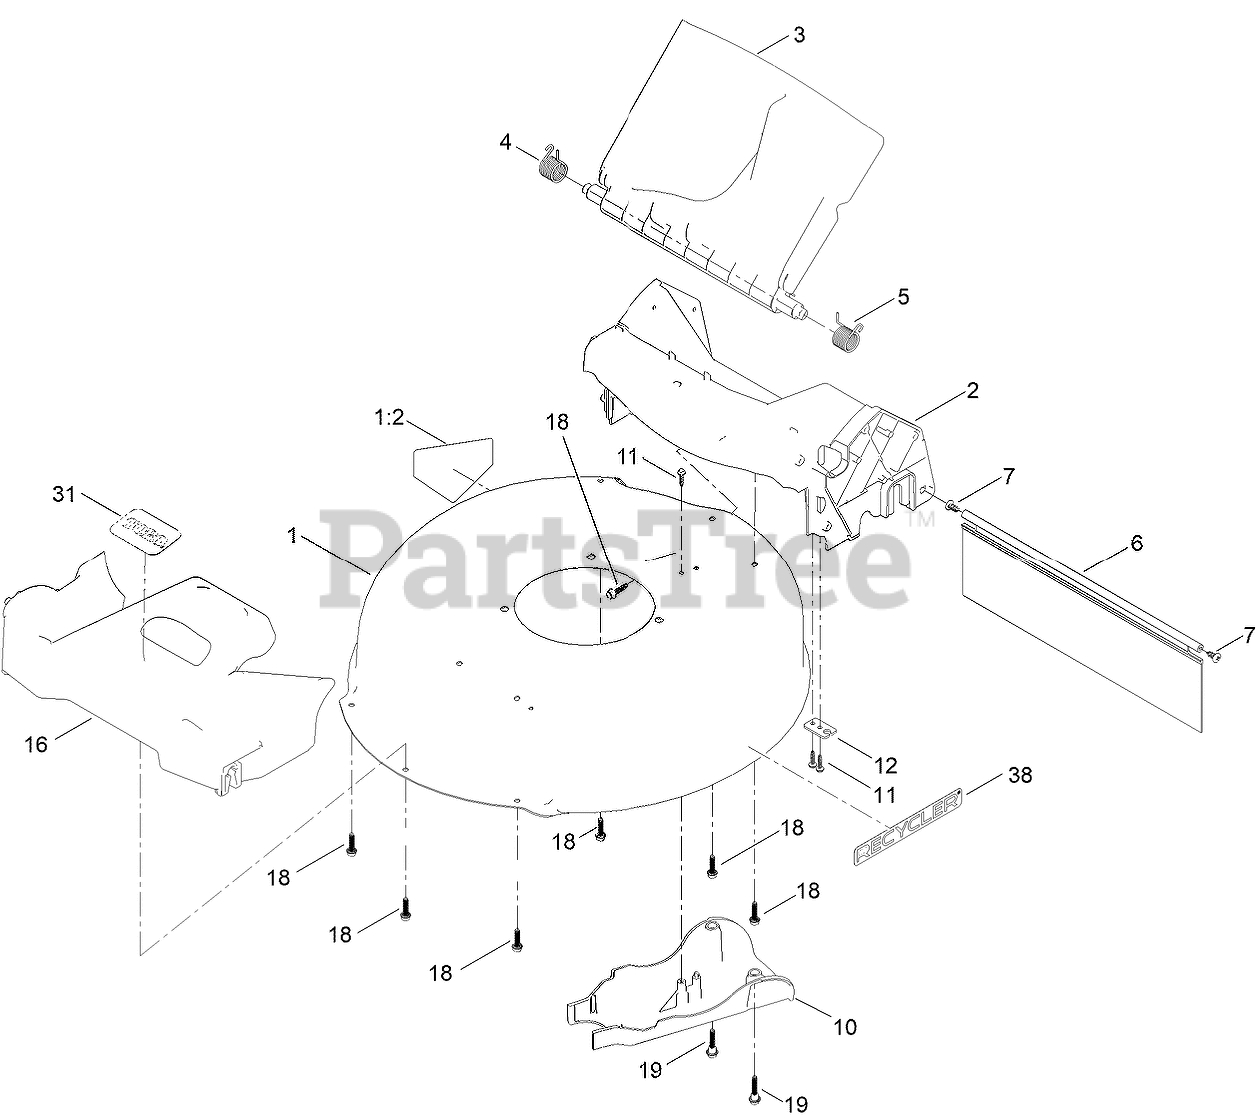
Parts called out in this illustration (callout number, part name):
1	HOUSING ASM
1:2	DECAL-DANGER
2	CHUTE-SP/AWD, 21 IN
3	DEFLECTOR-REAR ASM
4	SPRING-TORSION
5	SPRING-TORSION
6	SHIELD-TRAILING
7	SCREW-PTH
10	COVER-BELT
11	SCREW-HWH
12	BRACKET-CABLE
16	BUMPER
18	SCREW-FLANGE, PLASTIC
19	SCREW-SHOULDER, HHF
31	DECAL-TORO, SILVER
